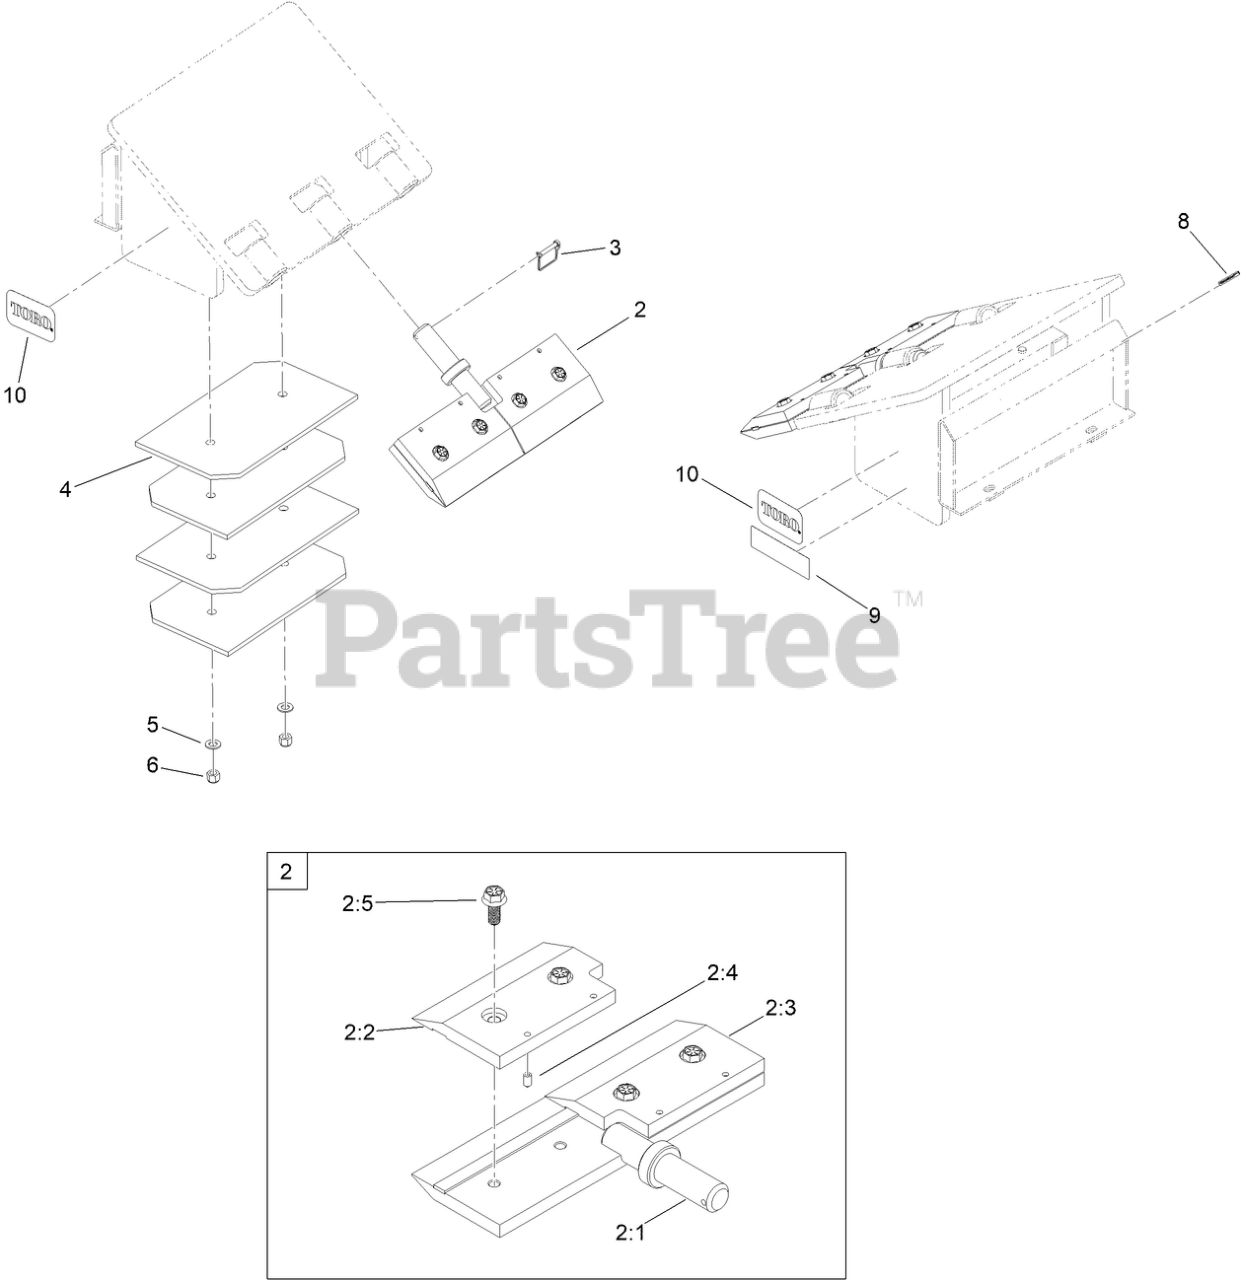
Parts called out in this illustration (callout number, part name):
2	HOLDER-BLADE ASM
2:1	HOLDER-BLADE BASE
2:2	CLAMP-HOLDER, 24" BLADE
2:3	CLAMP-HOLDER, 24" BLADE
2:4	SCREW-SET, HSH
2:5	BOLT-BLADE HOLDER
3	PIN-HITCH
4	WEIGHT
5	WASHER-FLAT
6	NUT-LOCK, NI
8	DECAL-WARNING
9	DECAL-SAFETY, SCRAPER
